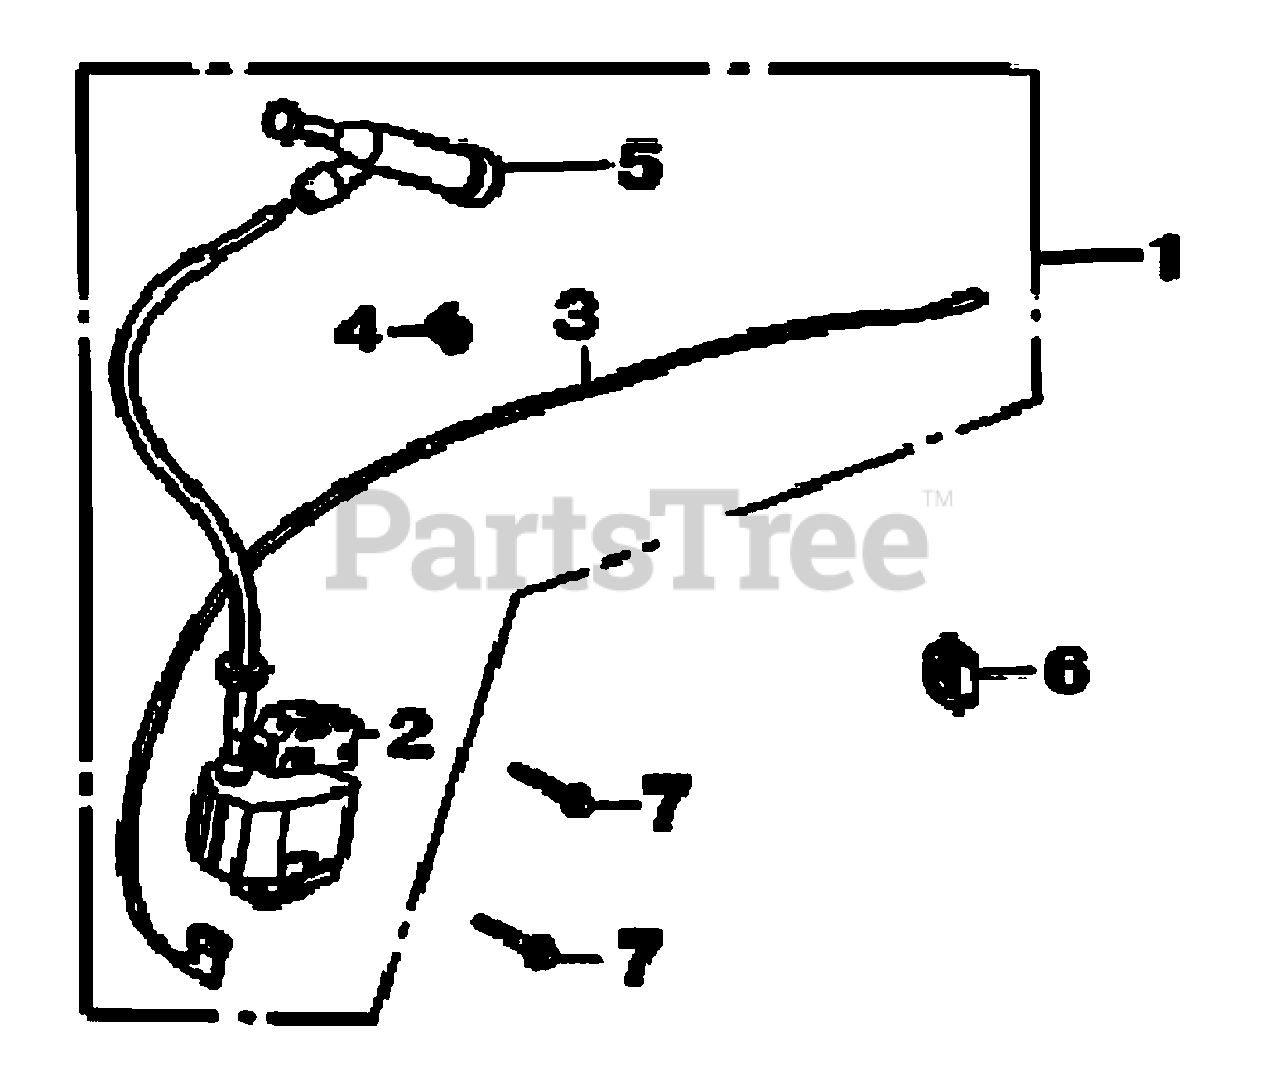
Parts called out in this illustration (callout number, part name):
1	COIL ASSY. IGNITION
2	COIL, IGNITION
3	CORD, STOP SWITCH
4	HOLDER, STOP SWITCH
5	CAP ASSY., NOISE SUPPRESSOR
6	GROMMET, CORD
7	BOLT, FLANGE
